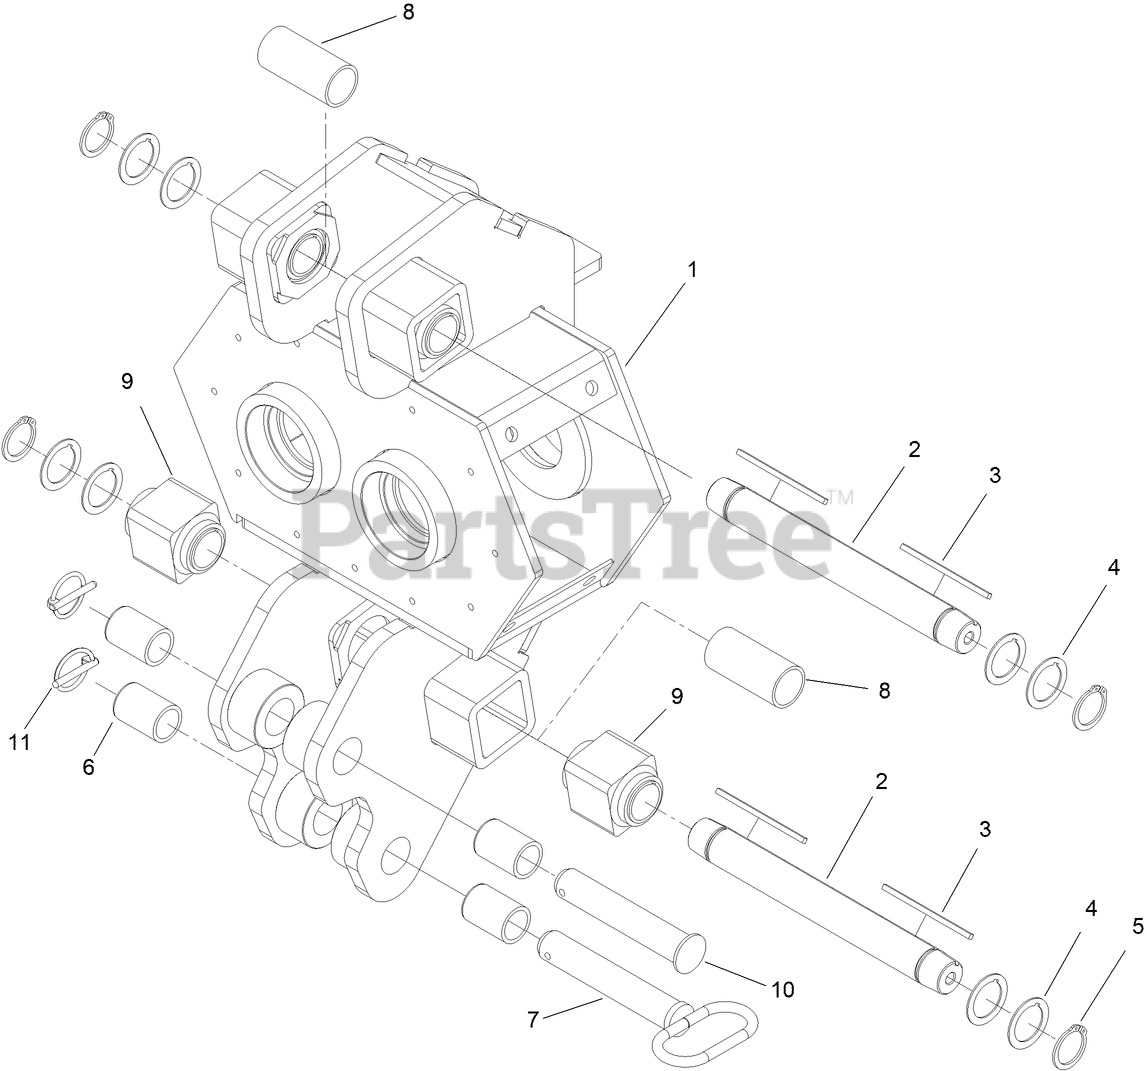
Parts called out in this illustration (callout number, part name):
1	VIBRATOR BOX - MACHINING
2	SHAFT-ARM, PLOW
3	KEY-SQUARE
4	SHIM-ARM
5	RING-RETAINING
6	BUSHING
8	TUBE-SPACER
9	JOINT-CT BD, J-8203
10	PIN-MOUNTING, BLADE
11	KLIK PIN ASM
